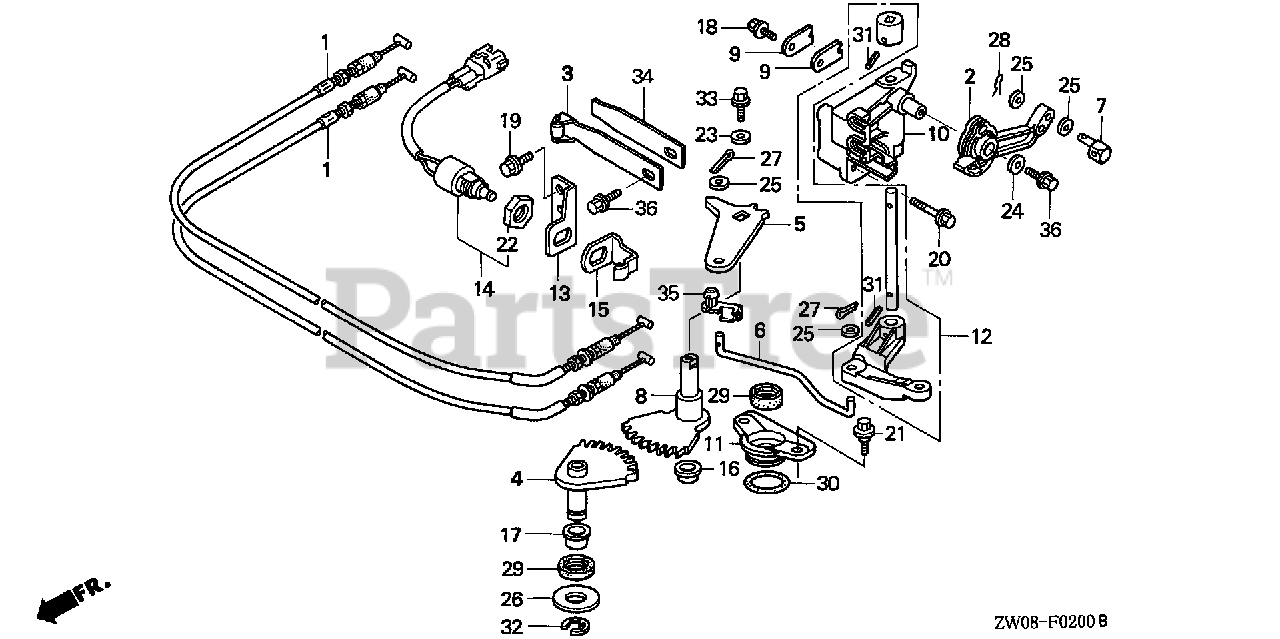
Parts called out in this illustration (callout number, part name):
1	CABLE, THROTTLE
2	ARM, THROTTLE
3	SPRING, CLICK
4	SHAFT, SHIFT (A)
5	ARM, SHIFT
6	ROD, LINK
7	PIVOT, SHIFT
8	SHAFT, SHIFT (B)
9	PLATE, SHIFT SHAFT
10	BRACKET, SHIFT LINK
11	HOLDER, SEAL
12	LINK, SHIFT
13	BRACKET, NEUTRAL SWITCH
14	SET,NEUT SW
15	PLATE, NEUTRAL SWITCH
16	BUSH, TORQUE LINK
17	BUSH (14X10)
18	BOLT, FLANGE (6X12) (CT200)
19	BOLT, FLANGE (6X14) (CT200)
20	BOLT, FLANGE (6X35)
21	BOLT, FLANGE (6MM)
22	NUT, HEX. (20MM) Use up to Frame SN 1300359.
23	WASHER (6MM)
24	WASHER, PLAIN (6MM)
25	WASHER, PLAIN (6MM) Use from Frame SN 4800713.
27	PIN, SPLIT (2.0)
28	PIN, SPECIAL LOCK (6MM)
29	SEAL, WATER (14X26X6)
30	O-RING (27X2) (ARAI)
31	PIN, SPRING (3X18)
32	E-RING (12MM)
33	BOLT, FLANGE (6X12)
34	SPRING, CLICK ASSIST
35	BUSH, SHAFT
36	BOLT, FLANGE (6X14) (CT200)
